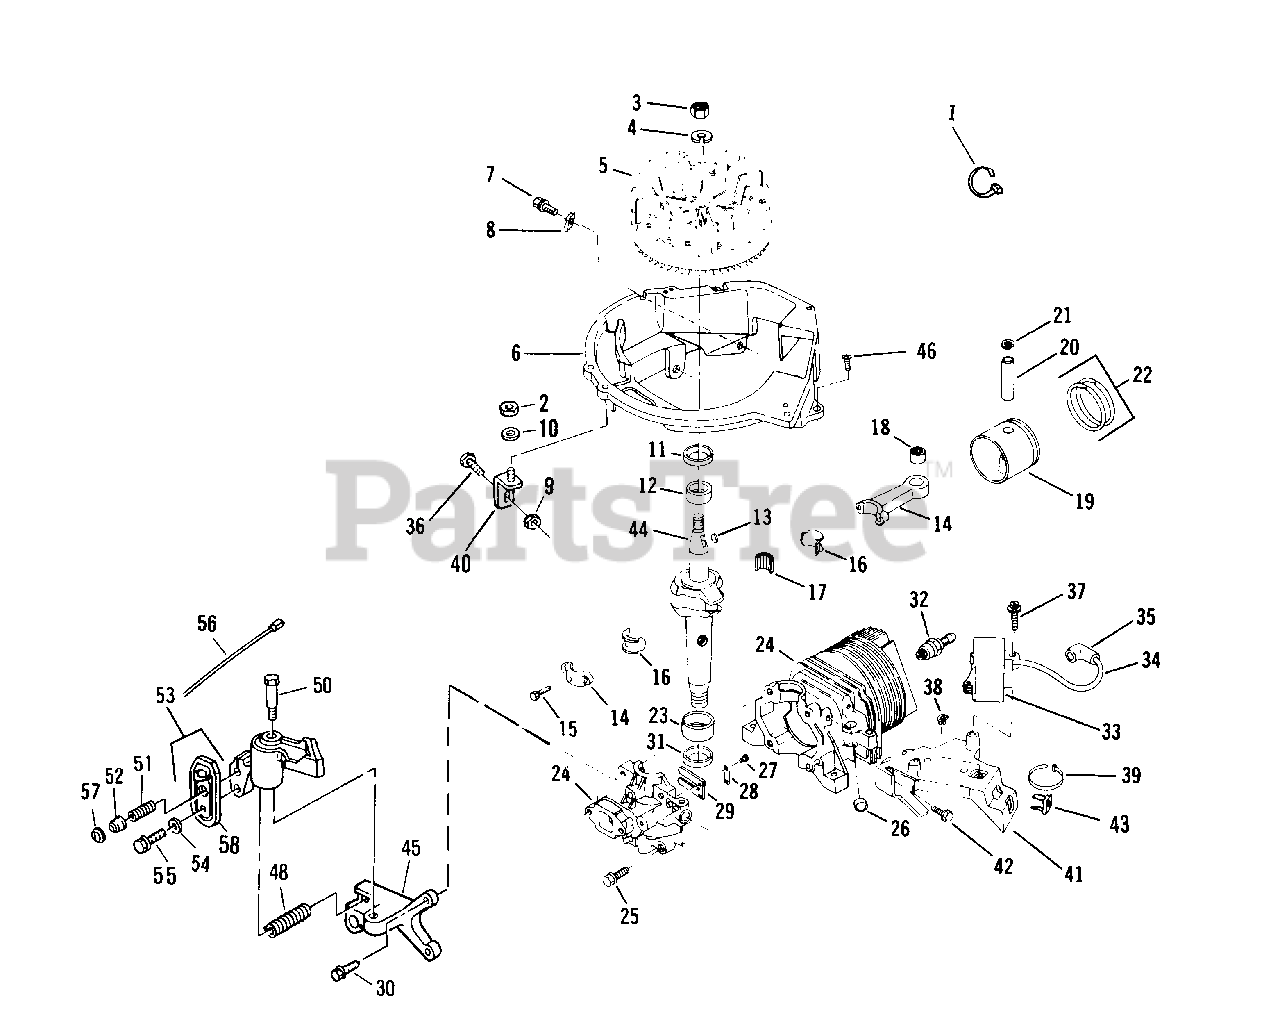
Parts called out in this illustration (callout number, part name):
1	Tie Strap
2	Nut
3	Nut-Flywheel
4	Lockwasher
5	Flywheel Assembly
6	Base-Shroud
7	Screw
8	Clip-"J"
9	Nut
10	Washer
11	Oil Seal-Upper
12	Bearing-Main-Upper
13	Key-Flywheel
14	Connecting Rod Assembly
15	Screw-Cap
16	Liner Split
17	Needle Bearing Set
18	Bearing Assembly
19	Piston and Ring Set
20	Wrist Pin
21	Retaining Ring
22	Ring Set
23	Bearing-Main-Lower
24	Cylinder and Crankcase Cover Asy.
25	Screw-Cover to Crankcase
26	Plug
27	Screw-Reed to Crankcase Cover
28	Plate-Reed Hold Down
29	Reed
30	Screw-Brake Mounting Brkt.
31	Oil Seal-Lower
32	Spark Plug
33	C.D. Ignition Module & Lead Asy.
34	High Tension Lead and Lower Assembly
35	Spring Terminal
36	Bolt
37	Screw-C.D. Mounting
38	Grommet-C.D. Bracket
39	Tie Strap
40	Brace Assembly
41	Bracket-C.D. Mounting
42	Screw
43	Grommet
44	Crankshaft
45	Bracket-Brake
46	Screw-Shroud Base to C.D. Bracket
48	Spring-Brake
49	Brake Assembly
50	Bolt-Shoulder
51	Spring Cable-Retainer
52	Actuator-Brake Lever
53	Switch Assembly
54	Washer
55	Bolt
56	Lead Assembly
57	Retainer
58	Case Assembly-Only
